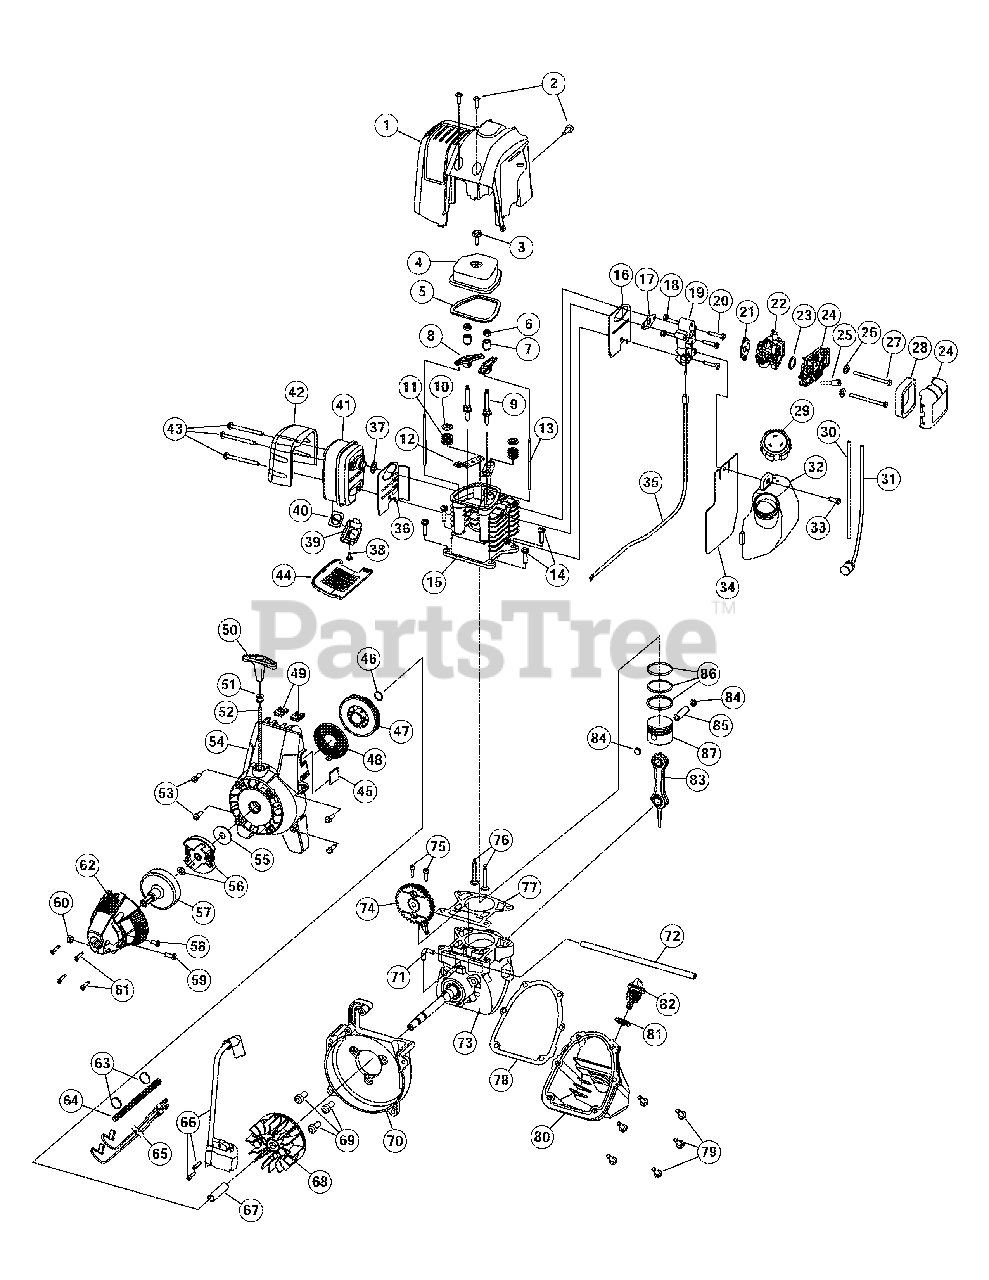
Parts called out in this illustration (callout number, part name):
1	Engine Cover
2	Engine Cover Screws
3	Valve Cover Screw
4	Valve Cover
5	Valve Cover Gasket
6	Rocker Adjustment Nut
7	Rocker Arm Pivot
8	Rocker Arm
9	Rocker Arm Stud
10	Valve Spring Retainer
11	Valve Spring
12	Push Rod Guide
13	Push Rod
14	Cylinder Screw
15	Cylinder Assembly (includes 9, 12, 15, 76 & 77)
16	Intake Baffle
17	Carburetor Mount Gasket
18	Nut
19	Carburetor Mount (includes 18)
20	Carburetor Mount Screw
21	Carburetor Gasket
22	Carburetor with Primer
23	O-Ring, Carburetor
24	Air Filter Assembly
25	Breather Tube
27	Air Filter Mounting Screw
28	Air Filter
29	Fuel Cap
30	Fuel Return Line
31	Fuel Pick-Up Line with Filter
32	Fuel Tank Assembly (includes 29-31)
33	Screw
34	Fuel Tank Shield
35	Throttle Cable
36	Muffler Baffle
37	Muffler Gasket
39	Screen Cover
40	Spark Arrestor Screen
41	Muffler (includes 37-40)
42	Heat Shield
43	Muffler Mounting Screw
44	Muffler Cover
45	Grommet
46	Pulley Retainer
47	Recoil Pulley
48	Recoil Spring
49	Nut Clip
50	Pull Handle
51	Rope Guide
53	Starter Housing Screw
54	Starter Housing Assembly (includes 46-53)
55	Clutch Washer
56	Clutch with Spacer
57	Clutch Drum
58	Anti-Rotation Screw
59	Screw
61	Clutch Cover Screw
62	Clutch Cover
63	Cable Clamp
64	Wire Cover
65	Wire Leads
66	Ignition Module Assembly
68	Flywheel
69	Shroud Screw
70	Shroud Assembly (includes 69)
71	90° Elbow
72	Breather Hose
73	Crankcase Assembly (includes 71 & 72)
74	Cam Bracket Assembly
75	Cam Bracket Screw
76	Valves, Intake and Exhaust
77	Cylinder Gasket
78	Oil Pan Gasket
79	Oil Pan Screw
80	Oil Pan (includes 78 & 79)
82	Dipstick Assembly (includes 81)
83	Connecting Rod
84	Wrist Pin Button
85	Wrist Pin
86	Piston Ring Set
87	Piston (includes 86)
